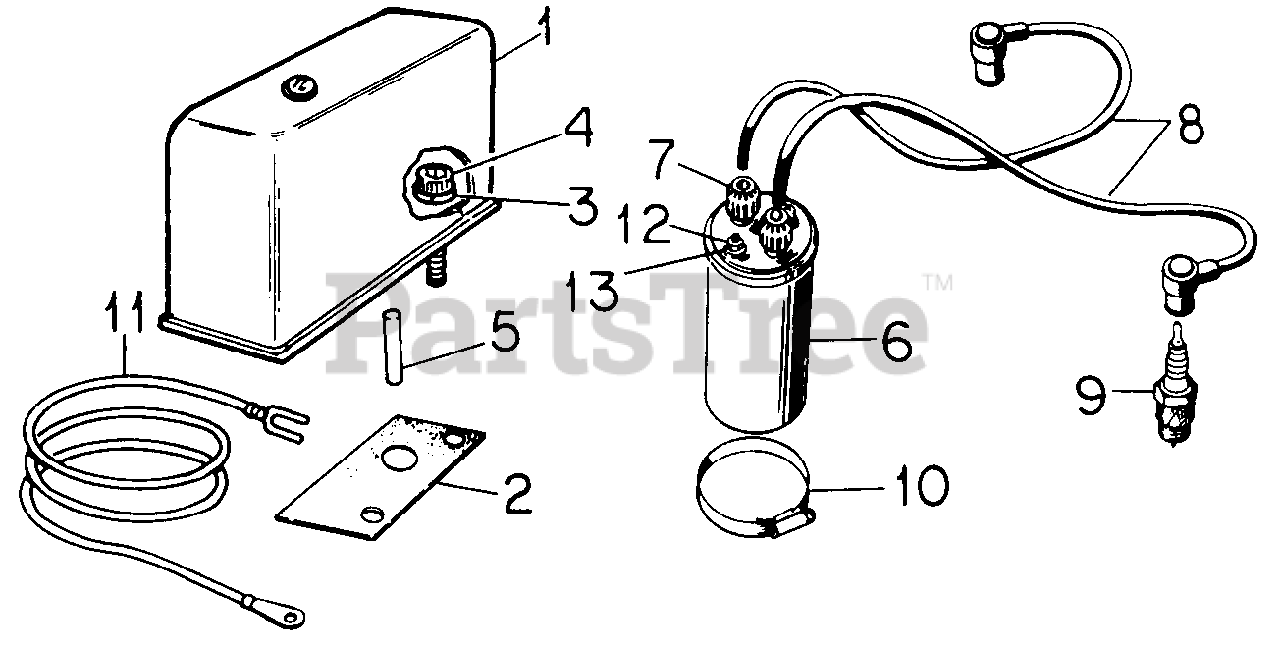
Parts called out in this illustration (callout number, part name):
1	Box Assy, Breaker
2	Gasket
3	Washer, 1/4 Lock
4	Screw, 1/4 X 3/4 H/Shd Cap
5	Plunger, Breaker Point Assy
6	Coil, Ignition
7	Cap, Ignition Coil
8	Kit, Spark Plug Cable
9	Plug, Spark
10	Clamp, Coil
11	Cable Assy, Block to Coil
12	Nut, Special Hex
13	Washer, Lock
